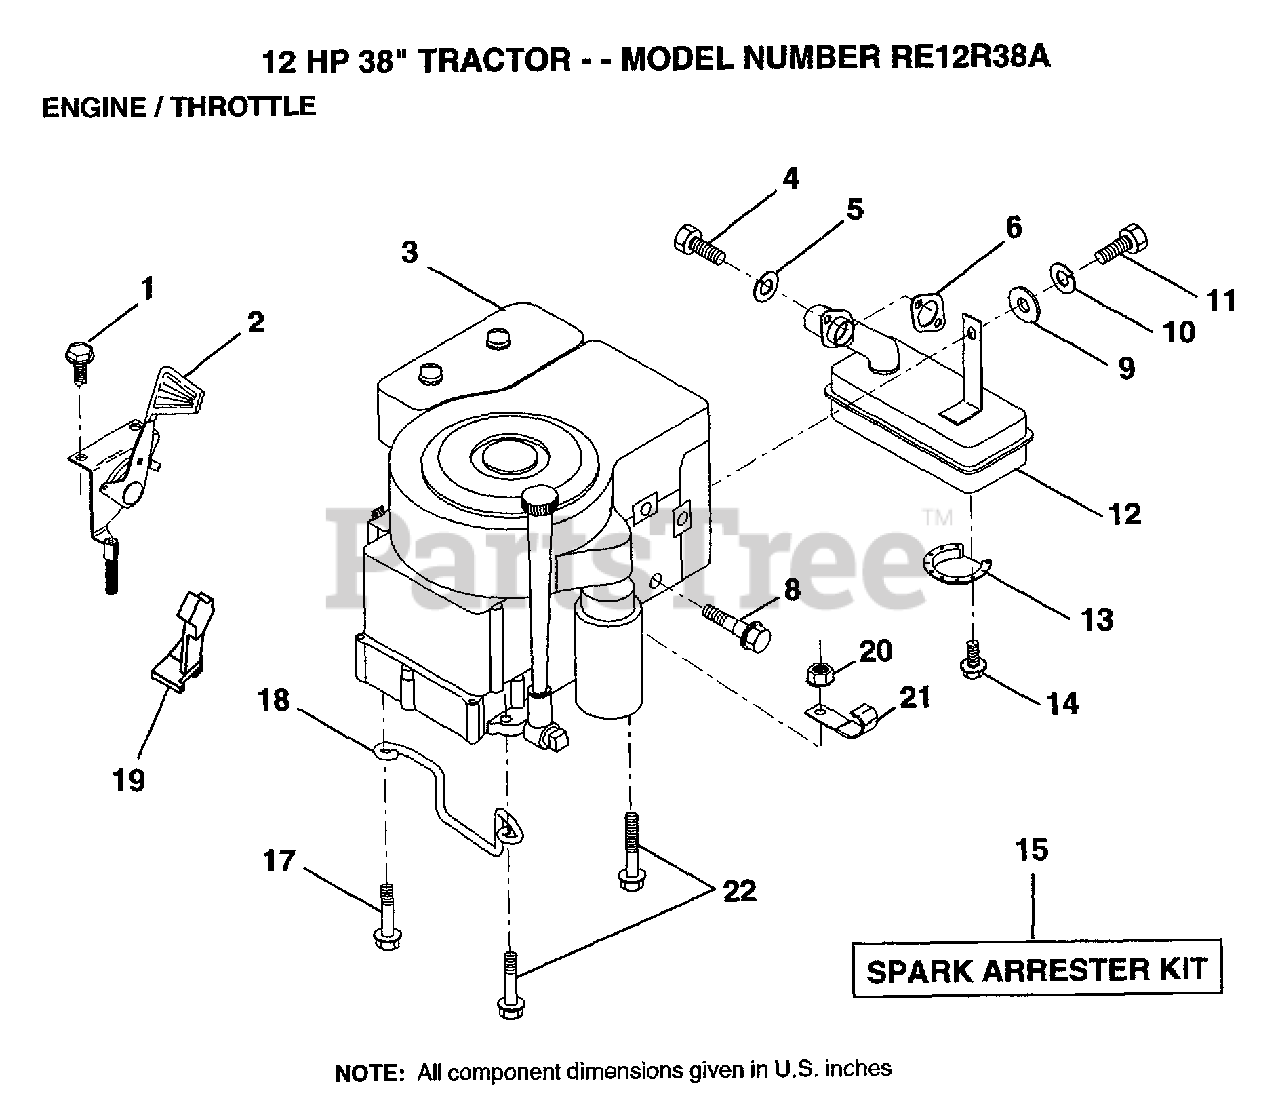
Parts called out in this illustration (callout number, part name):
1	SCREW
2	THROTTLE CONTROL
4	SCREW
5	LOCKWASHER
8	BOLT T
10	LOCKWASHER
13	DEFLECTOR.222573
17	SCREW LT
18	KEEPER,DR BELT GR
19	"STOP,DASH THROTT"
20	NUT
21	CLIP T
22	SCREW LT
